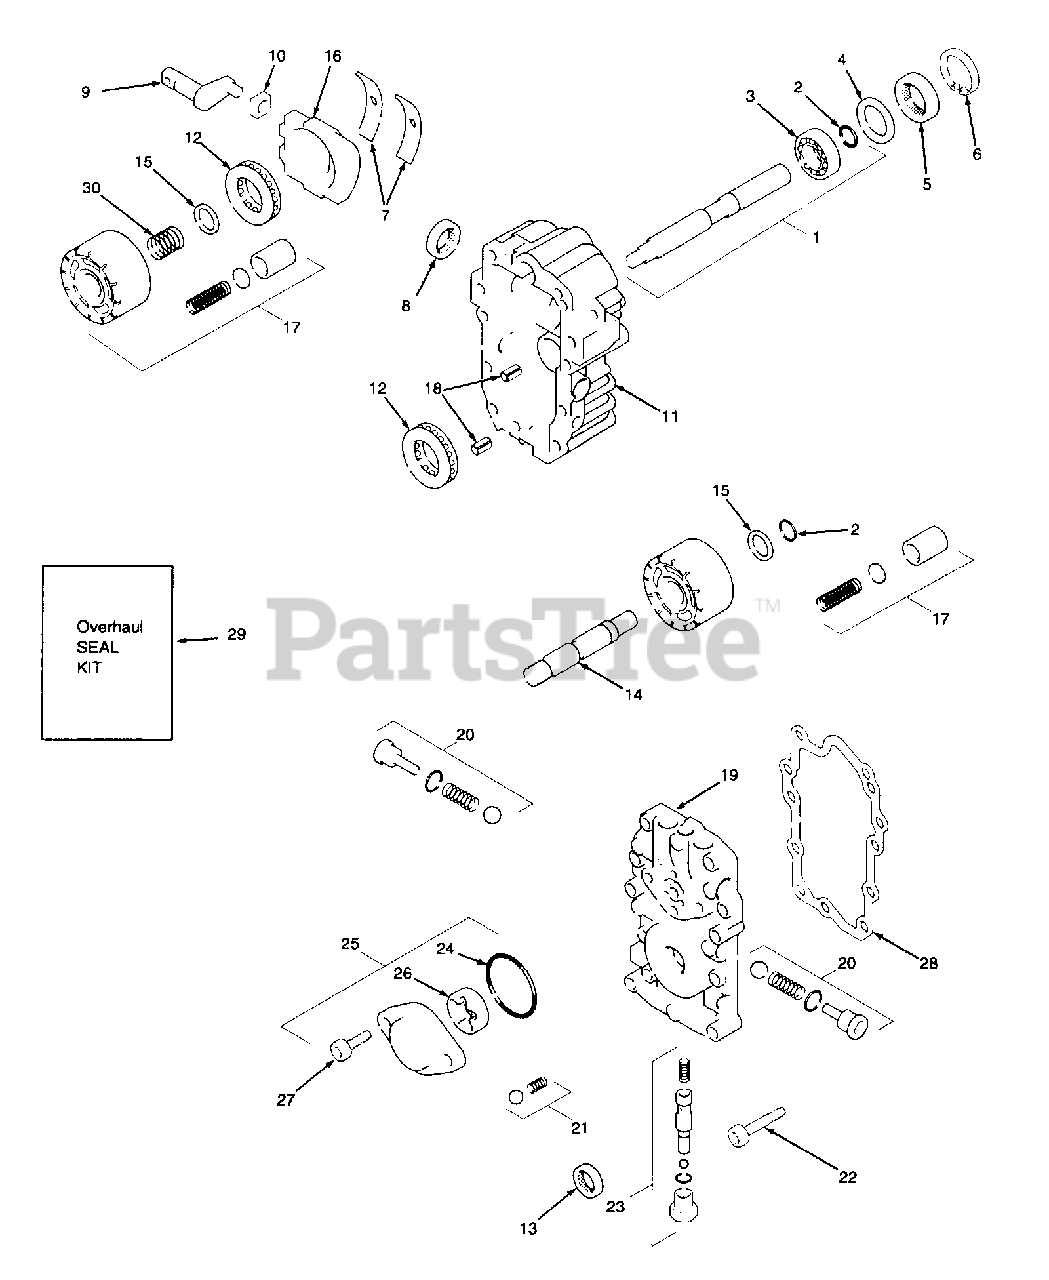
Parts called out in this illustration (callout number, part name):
1	Pump Shaft Kit
2	Wire Retaining Ring
3	Ball Bearing
5	Lip Seal (16 x 35 x 7)
6	Retaining Ring
7	Cradle Bearing
8	Lip Seal (12 x 35 x 7)
9	Trunnion Arm
10	Slot Guide
11	Transmission Housing Kit RH
12	Thrust Ball Bearing Assembly
13	Lip Seal (15 x 24 x 7)
14	Motor Shaft
15	Block Thrust Washer
16	Variable Swash Plate
17	BDP-10L Block Assembly
18	Pin ST Holder
19	Center Section Kit
20	Check Valve Kit
21	Charge Relief Kit
22	Socket Head Cap Screw
23	Bypass Valve Kit
25	Charge Pump Cover
26	Gerotor Assembly
27	Capscrew (6mm x 20")
28	Center Section Gasket
29	Overhaul Seal Kit
30	Spring Block
